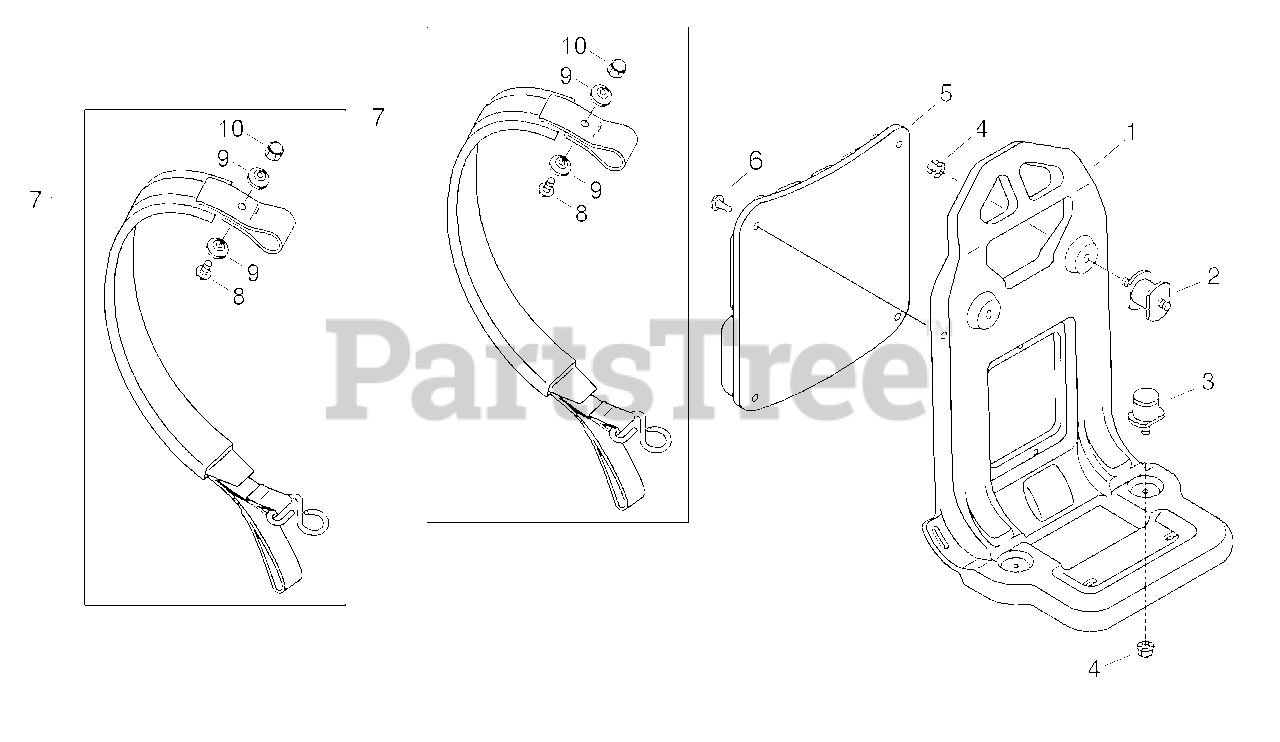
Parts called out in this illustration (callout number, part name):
1	FRAME, BACKPACK
2	CUSHION 6
3	CUSHION 6
5	CUSHION, BACKPACK
7	HARNESS ASSY
8	SCREW 5×16
9	WASHER 5.2×22×2.0
10	NUT, LOCK M5
